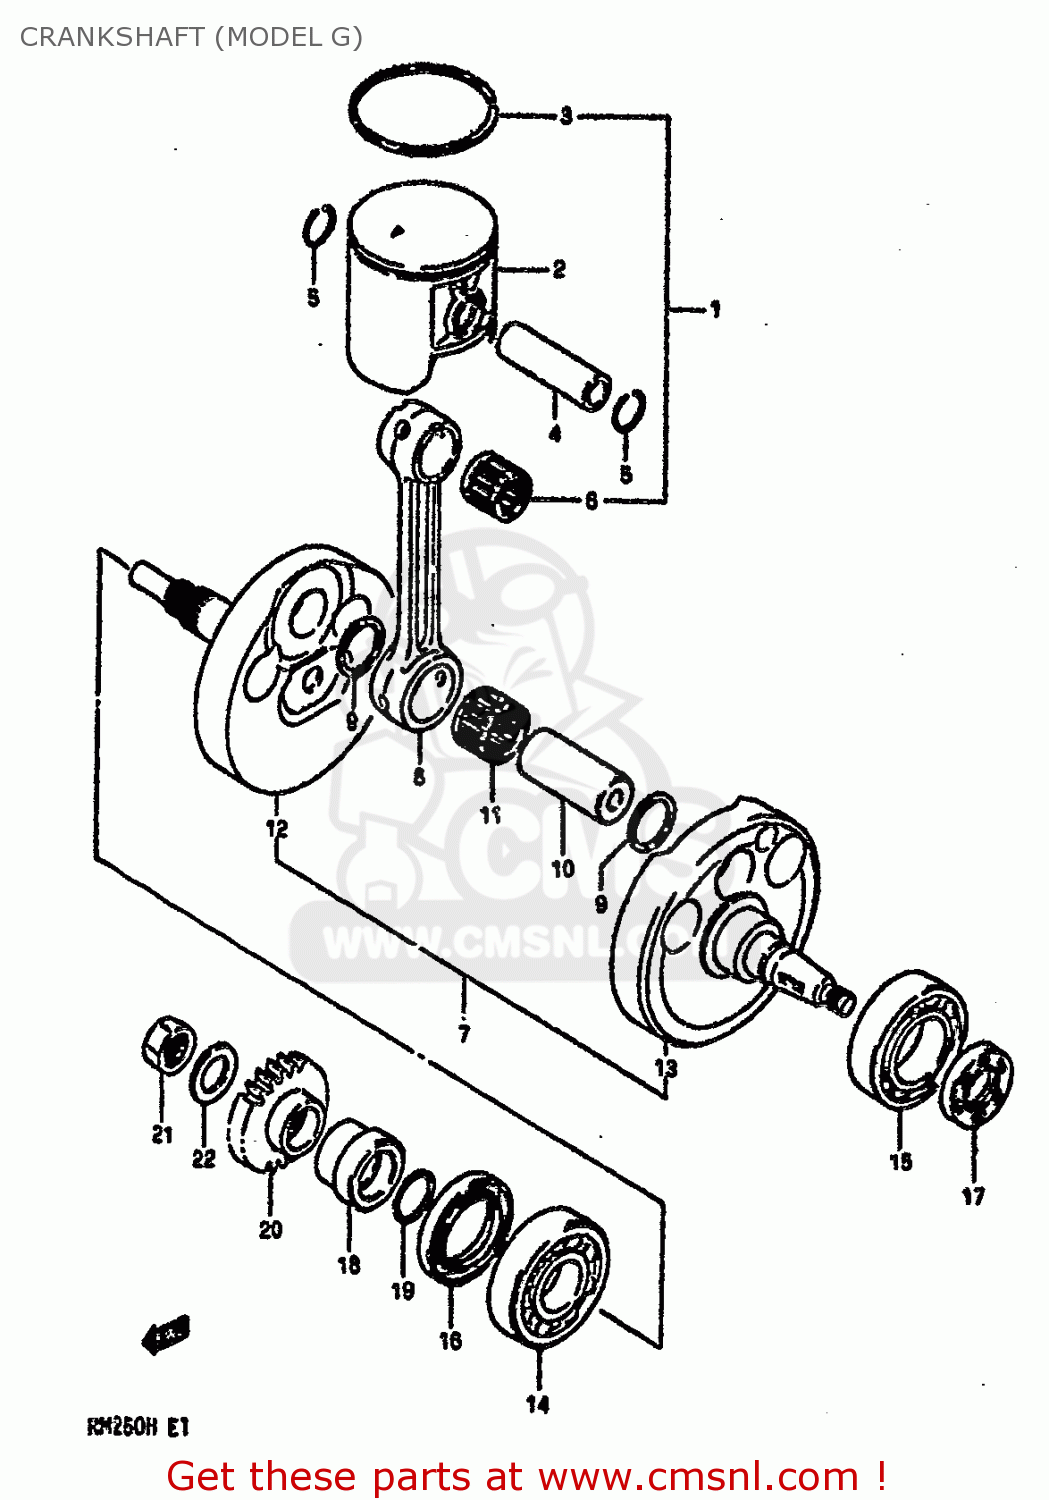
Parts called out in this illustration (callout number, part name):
1	PISTON KIT (STD)
2	PISTON
3	RING,PISTON
4	PIN,PISTON (18MM)
5	CIRCLIP,PISTON PIN
6	BEARING(18X23X22)
7	CRANKSHAFT ASSEMBLY
8	CONNECTION ROD
9	WASHER(24X29X1.5)
10	PIN,CRANK
11	BEARING
12	CRANKSHAFT,RIGHT
13	CRANKSHAFT,LEFT
14	BEARING(25X62X17)
15	BEARING(30X62X16)
16	SEAL,OIL(36X52X8)
17	OIL SEAL
18	SPACER,PRIMARY DRIVE GEAR
19	O RING(D:2.4,ID:21.8)
20	GEAR,PRIMARY DRIVE
21	NUT
22	WASHER
